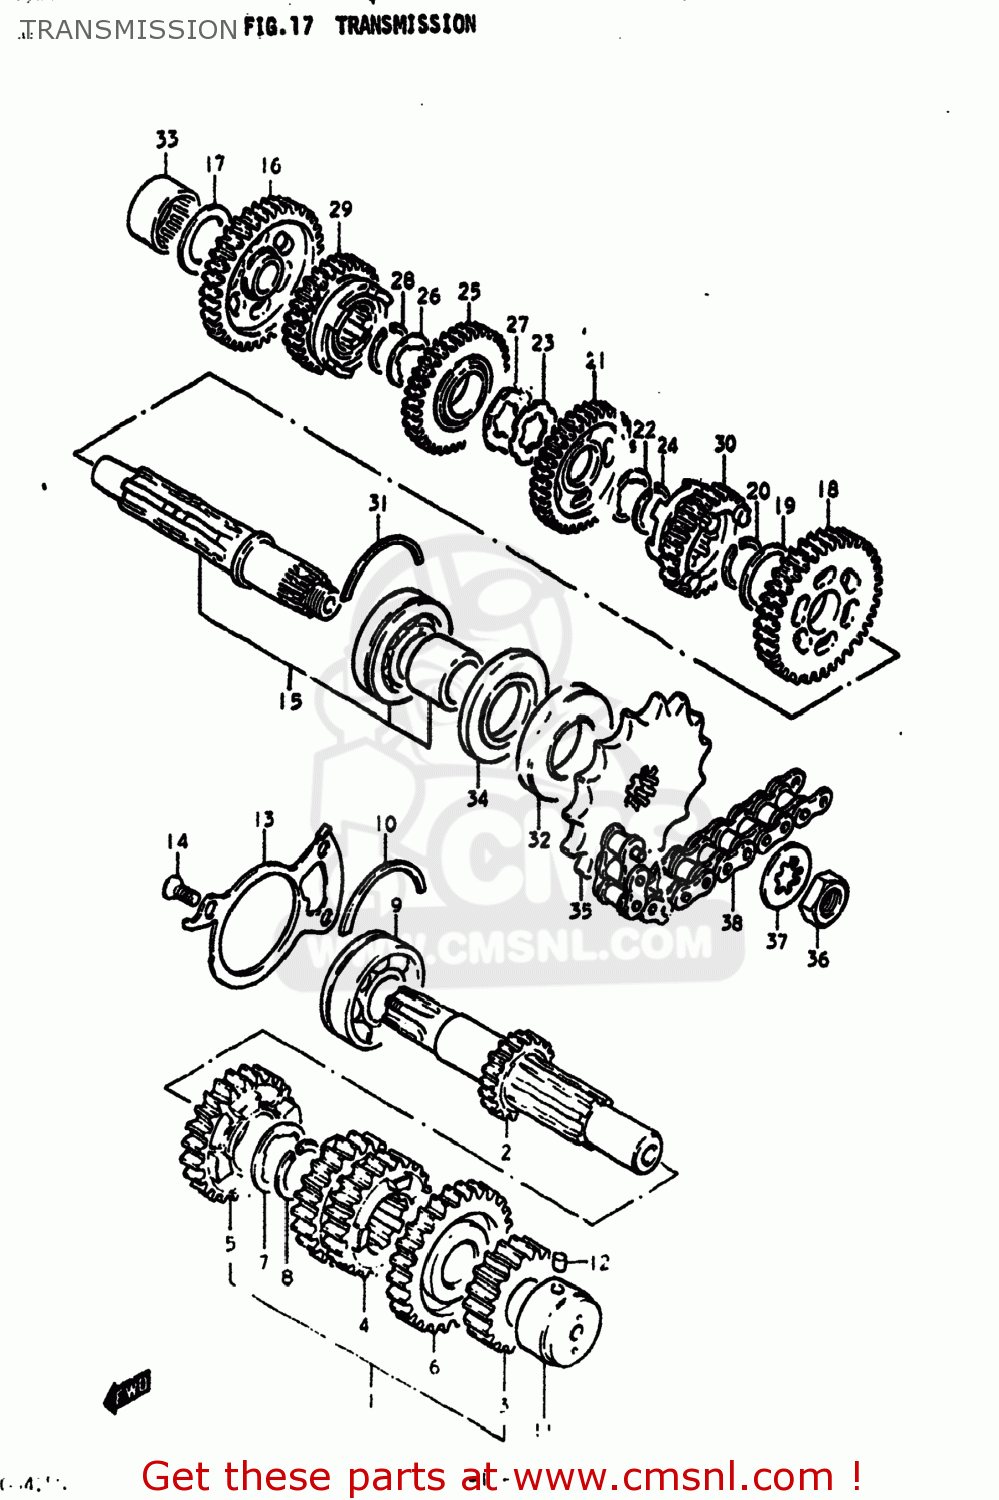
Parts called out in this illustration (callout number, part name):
1	SHAFT,COUNTER
2	SHAFT,COUNTER
3	GEAR,2ND DRIVE(NT:18)
4	GEAR,THIRD DRIVE
5	GEAR,FIFTH DRIVE
6	GEAR,SIXTH DRIVE
7	WASHER
8	CIRCLIP
9	BEARING(25X62X17)
10	C-RING
11	ROLLER BEARING (20X34X2
12	PIN
13	PLATE,COUNTERSHAFT BEARING
14	SCREW
15	SHAFT,DRIVE
16	GEAR,FIRST DRIVEN
17	WASHER
18	GEAR,SECOND DRIVEN
19	WASHER
20	CIRCLIP
21	GEAR,THIRD DRIVEN
22	WASHER,LOCK
23	WASHER,LOCK
24	CIRCLIP
25	GEAR,FOURTH DRIVEN
26	WASHER,LOCK
27	WASHER
28	CIRCLIP
29	GEAR,5TH DRIVEN(NT:25)
30	GEAR,SIXTH DRIVEN
31	C-RING
32	OIL SEAL
33	ROLLER BEARING (20X34X1
34	SEAL,OIL(32X62X5.5)
35	SPROCKET,ENGINE(NT:16)
36	NUT
37	WASHER
38	CHAIN ASSEMBLY,DRIVE
